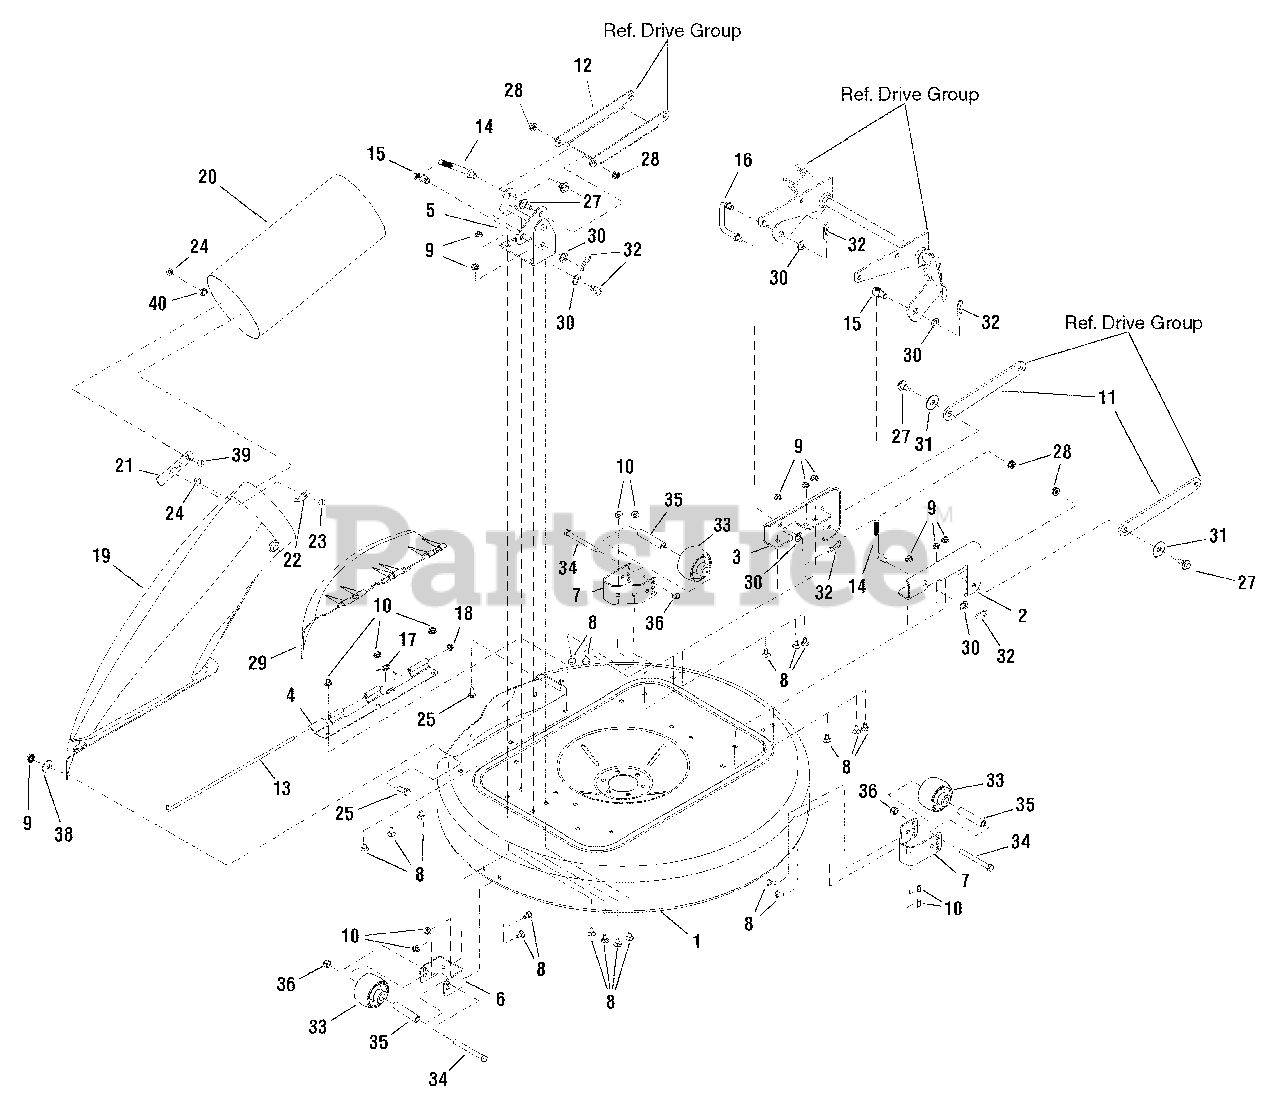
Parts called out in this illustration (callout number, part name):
1	BLADE HOUSING KIT, 33"
2	BRACKET, Top Deck LH
3	BRACKET, Top Deck RH
4	HINGE, Mulching Cover
5	FRONT DECK ADJUSTMENT ASSY
6	ANTI SCALP BRACKET, Front
7	ANTI SCALP BRACKET, Rear
8	BOLT, Carriage 5/16-18 x 5/8
9	NUT, Hex Flange, 5/16-18
10	NUT, Hex Flange Centerlock 5/16-18
11	ARM, Rear
12	HANGER, Front
13	ROD DEFLECTOR
14	ROD, Lift Link
15	ADJUSTING NUT
16	LIFT ROD, Fixed
17	SPRING, Deflector
18	PUSH CAP
19	REAR DISCHARGE CHUTE
20	CHUTE EXTENSION, Upper
21	RUBBER STRAP
22	PIN
23	BOLT, Carriage 1/4-20 x 0.63
24	NUT, Hex Flange Lock, 1/4-20
25	BOLT, Carriage, 5/16-18 x 3/4
27	BOLT, Shoulder, 3/8-16 x 1.10
28	NUT, Hex Flange, 3/8-16
29	MULCH COVER
30	WASHER, .51-.87
31	WASHER, .51-1.5
32	HAIRPIN
33	WHEELS, Anti Scalp
34	SCREW, 3/8-24 x 3/4" Hex Head Cap, GR5
35	SPACER, 3" Long
36	NUT, Hex Nyloc, 3/8-24
38	WASHER, Flat, 5/16
39	BOLT, 1/4-20 x 1.0
40	NUT, Keps Lock 1/4-20
